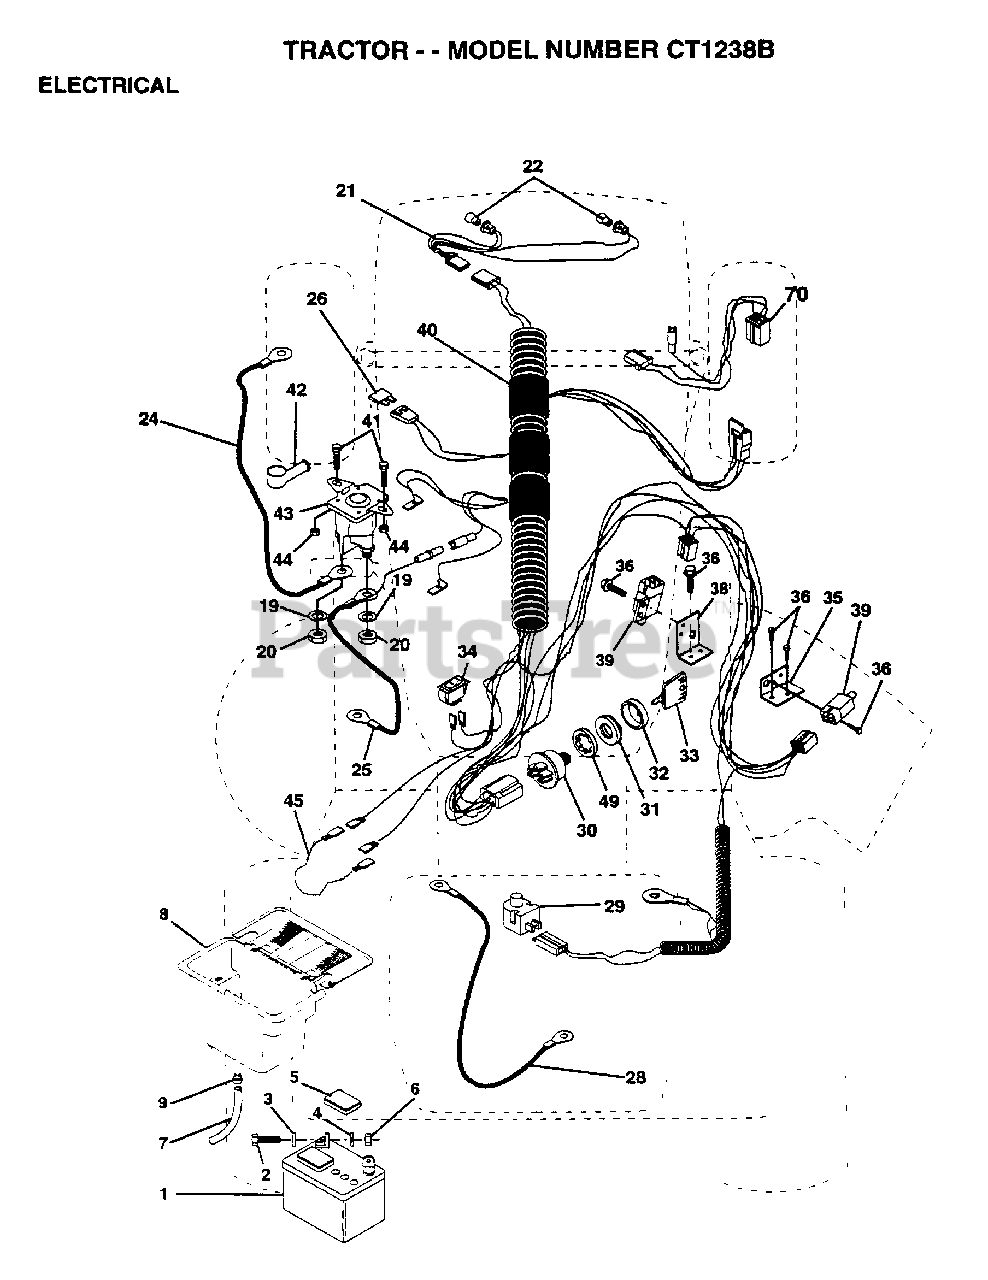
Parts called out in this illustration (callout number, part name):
2	BOLT LT
3	WASHER
4	LOCKWASHER
5	"CAP,BATTERY "
7	TUBE T
9	HOSE CLAMP T
20	NUT
21	"HARNESS,LIGHT SOC"
22	HEADLAMP BULB
24	"CABLE T, BATTERY"
25	CABLE.BTRY.6GA.RD
26	FUSE HYT
28	CABLE T
29	SWITCH SEAT
32	COVER KEY SWITCH
33	KEY MLD GEN DELTA
34	SWITCH LT
35	BRACKET LT
36	SCREW
38	BRACKET SWITCH IN
39	SWITCH INTERLOCKT
40	HARNESS.IGN.DASH.
41	BOLT.HX.1/4-20
44	NUT
45	ADAPTER AMMETER
49	LOCKWASHER
70	HARNESS ENG DUAL
